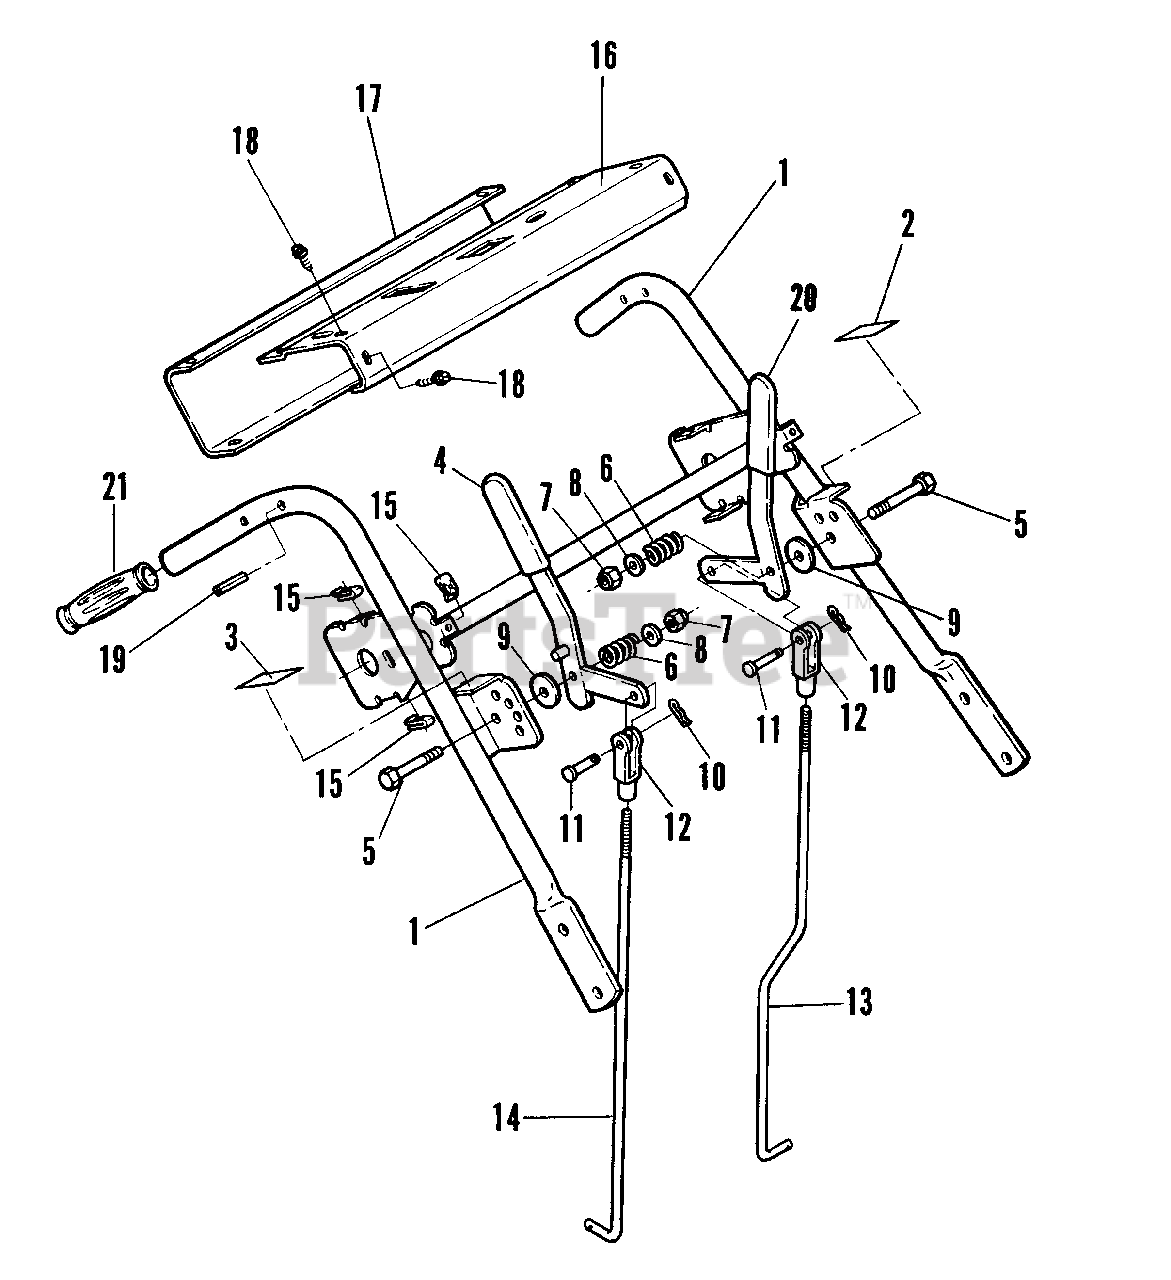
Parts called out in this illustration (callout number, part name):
1	HANDLE, Upper Weldment
2	DECAL, Blade
3	DECAL, Ground Speed
4	LEVER, Control W/Grip Assembly
5	SCREW, Hex Head Cap 3/8 - 16 x 2
6	SPRING, Compression
7	NUT, Nyloc Hex 3/8 - 16
8	WASHER, Flat 3/8 Std.
9	WASHER, Spacer
10	PIN, Hair No. 2
11	PIN, Clevis 5/16
13	LINKAGE, Blade
14	LINKAGE, Ground Speed
15	NUT, Clip
16	PANEL, Control W/Decals
17	LOWER COVER W/Decal
18	SCREW, Pan Head 10-24 x 5/8
19	PIN, Roll 5/16 x 1 1/8
20	LEVER, Blade W/Grip Assembly
21	GRIP
